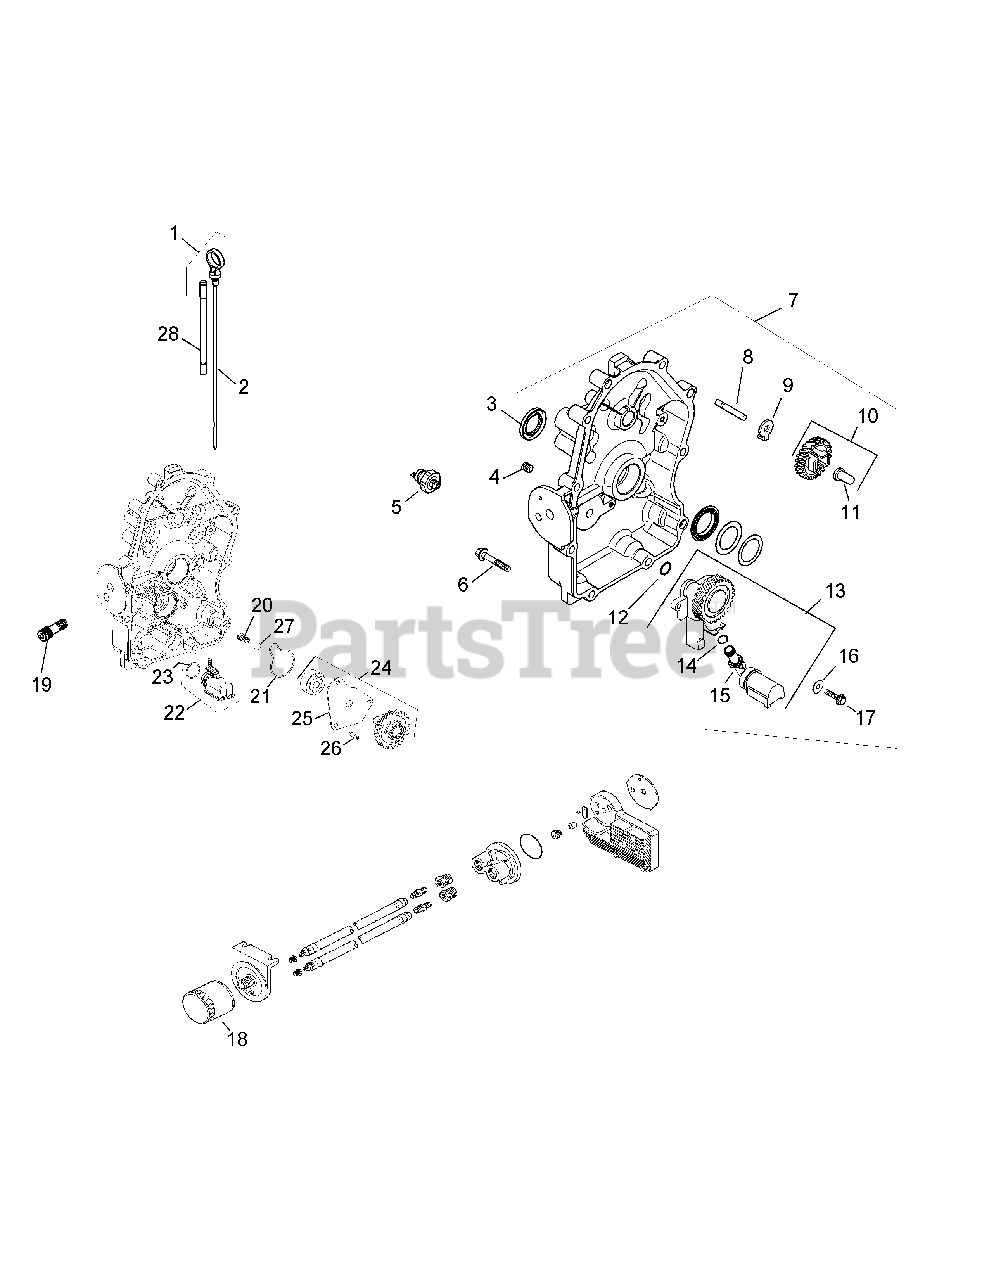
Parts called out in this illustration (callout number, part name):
1	Dipstick/Dipstick Tubes Kit
4	Countersink Pipe Plug, 1/8
5	Oil Pressure Switch
6	Flange Screw, M8 x 1.25 x 45
7	Closure Plate Assembly
8	Governor Gear Shaft
10	Governor Gear Kit w/ Pin
11	Governor Regulating Pin
13	Oil Pump Assembly Kit
14	Oil Pick-Up O-Ring
16	Flat Washer, 1/4 x 5/8
17	Thread Forming Screw
19	Oil Filter Nipple
20	Compression Spring
21	Oil Pump Cover Seal
22	Oil Pick-Up Assembly
23	Oil Pick-Up O-Ring
24	Oil Pump Assembly
25	Oil Pump Cover
26	Button Head Screw
27	Pressure Relief Ball
28	Dipstick Tube
